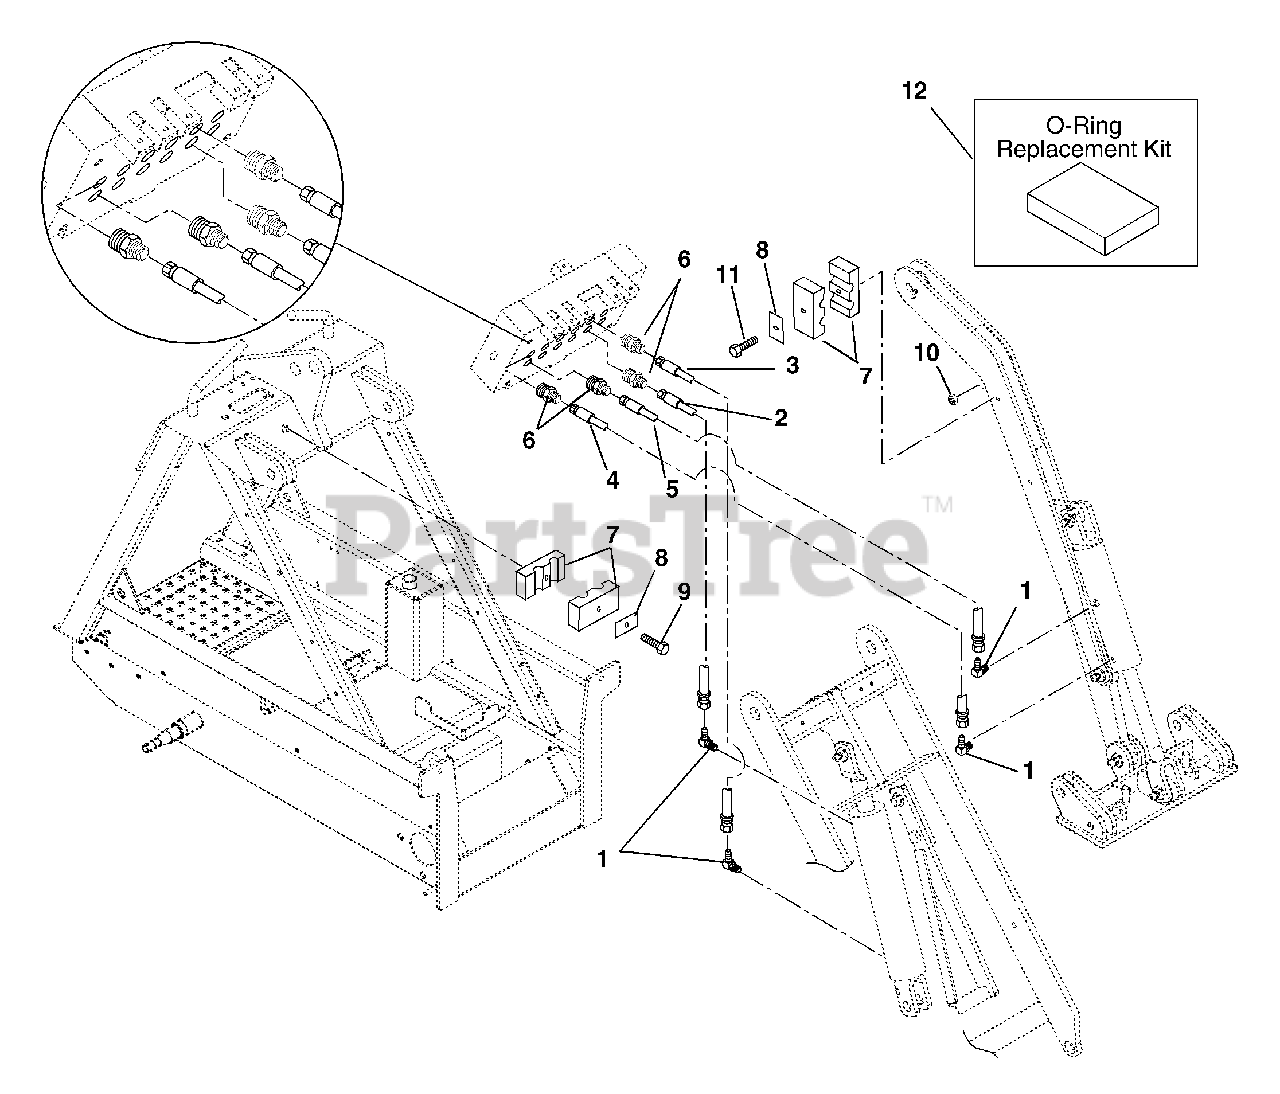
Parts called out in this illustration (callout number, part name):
1	Hydraulic, Fitting Elbow
2	Hose, Hydraulic .38-33-4K
3	Hose, Hydraulic .38-21-4K
4	Hose, Hydraulic .38-73-4K
5	Hose, Hydraulic .38-86-4K
6	Fitting, Hydraulic Straight
7	Clamp-Dual Hose .375 I.D.
8	Plate-Cover
9	Bolt-Hex M8 x 1.25 x 55
10	Nut-Locking-Nylon M10-1.5
11	Bolt, Hex M8-1.25 x 110
12	(Assorted O-Rings for Hydraulic Components to fittings) SAE
12	(Assorted O-Rings for Flat Face Seal Fittings and Hoses)
